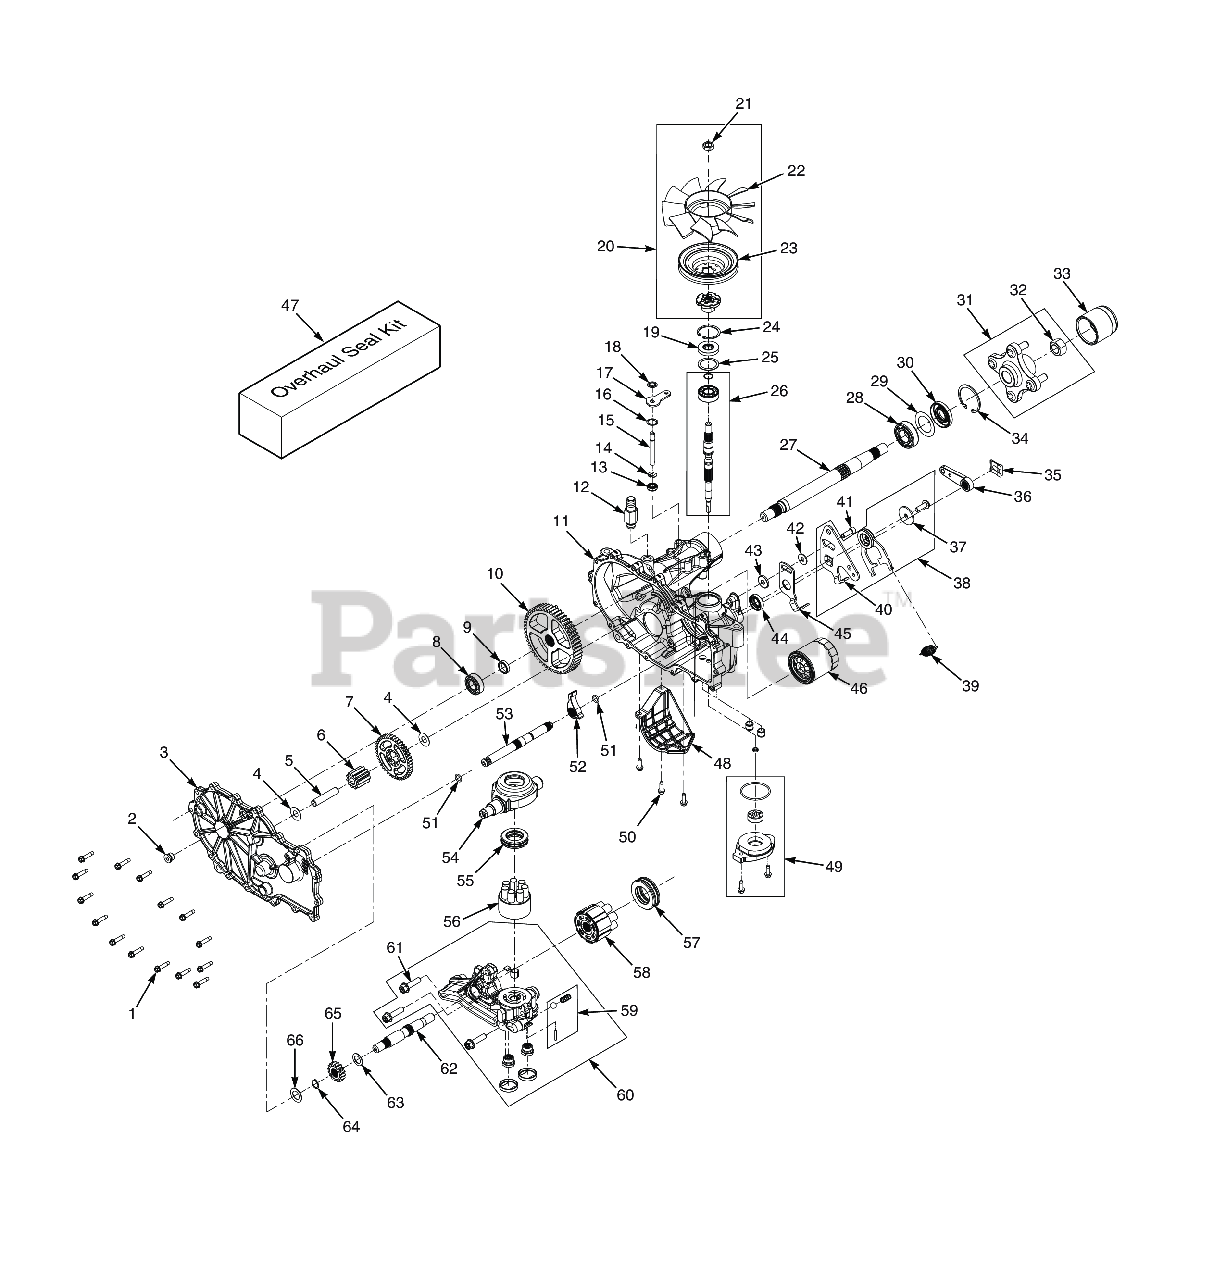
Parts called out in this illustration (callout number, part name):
1	Bolt, Hex Head 1/4-20 x 1-1/8"
2	Straight Thread Plug
3	Kit, Side Cover LH
3	Kit, Side Cover RH
4	Washer, .5 x 1.0 x .03
5	Jackshaft Pin
6	Gear, 11T
7	Gear, 43T
8	Bearing, Ball .75 x 40 x 12
9	Spacer, .750 x 1.320 x .257
10	Gear, 54T
11	Kit, Housing LH
11	Kit, Housing RH
12	Fitting, Transmission - SFZ61
13	Seal, Lip .375 x .75 x .25
14	Ring, .Retaining .375 External
15	Rod, By-Pass
16	R i n g , Retaining .750 Internal
17	Arm, By-Pass
18	Ring, Retainging .375 External
19	Seal, Lip 17 x 40 x 7
20	Kit, Fan & Pulley
21	Nut, Hex Locking 1/2-20
23	Pulley
24	R i n g , Retaining 2.06 Internal
25	Washer, 1.23 x 1.56 x .04
26	Kit, Shaft, Input
27	Kit, Shaft, Axle
28	Bearing, Ball 1.0 x 52 x 15 Open
29	Spacer, 1.355 x 2.035 x .021
30	Seal, Lip TC4 1.0 x 2.06 x .38
31	Hub Kit
32	Nut, Hex Locking 3/4-16
33	Cap, Axle
34	R i n g , Retaining 2.06 Internal
35	Clip, Retaining
36	Handle, Brake
37	Washer, .343 x 1.5 x .062
38	Kit, RTN Assembly
39	Spring, RTN
40	Arm, Control
41	Bolt, Hex Head Cap Screw 5/16-24 x 1" Patch
42	Washer, 7/16 x 7/8 OD x .06 HT
43	Spacer, .320 x 1.005 x .179
44	Seal, Lip 18 x 32 x 7
45	Arm, Neutral
46	Filter, Oil
47	Seal Kit
48	Filter Guard
49	Kit, Charge Pump
50	Bolt, 1/4-20 x 3/4"
51	O-Ring, -111 x .103 x 424
52	Pawl, Brake
53	Shaft, Brake
54	Trunnion, Swashplate
55	Ball Thrust Bearing
56	Kit, Cylinder Block
57	Thrust Ball Bearing Assembly
58	Kit, Motor Cylinder Block
59	Kit, Charge Relief
60	Kit, Center Section
61	Screw, Hex Flange Head 3/8-16 x 1-1/2"
62	Shaft, Motor
63	Washer, .72 x 1.16 x .04
64	Ring, Retaining .625
65	Gear, 16T
66	Washer, HT .62 ID x 1.0 OD x .05 Thick
